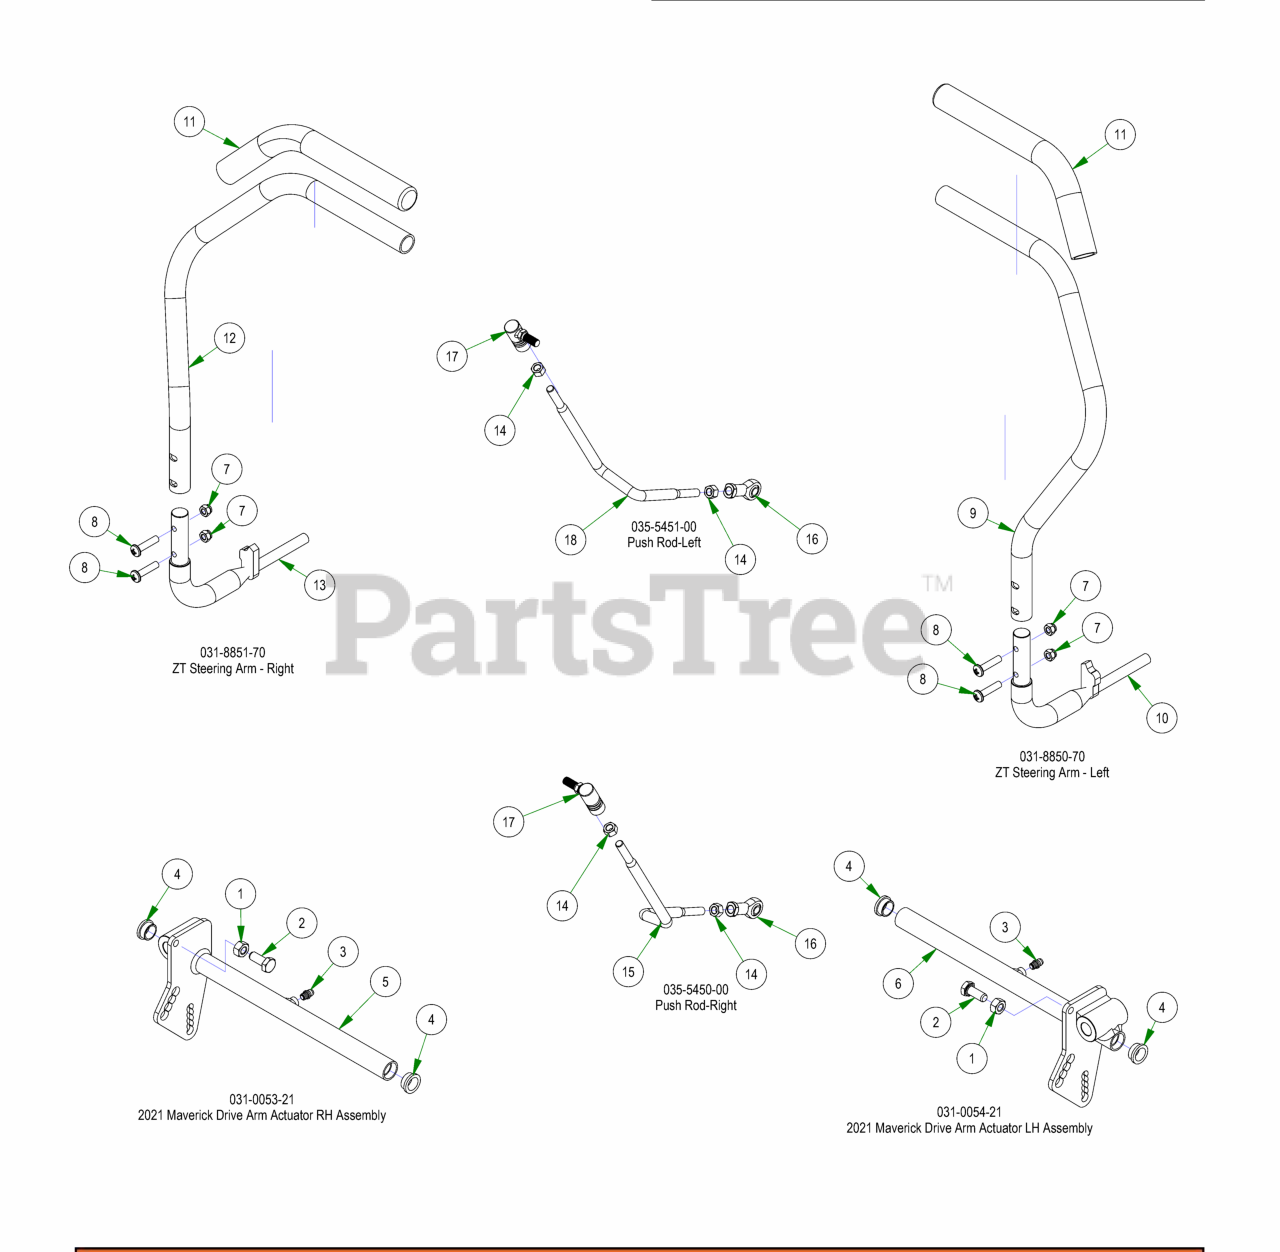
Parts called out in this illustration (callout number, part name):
1	5/16-18 HEX NUT ZINC
2	5/16-18 X 3/4 HEX CAP SCREW (GR.5) ZINC
3	1/4" Press in Grease Fitting
4	2019 Drive Arm Bushing
5	2021 Drive Actuator RH Weldment
6	2021 Drive Actuator LH Weldment
7	5/16-18 NYL INS L/N ZC
8	5/16-18 x 1 3/8" Futton Head Torx Drive Bolt
9	ZT Direction Steering Arm (Left)
10	Steering Arm Elbow (Left)
11	Rubber Grip
12	ZT Direction Steering Arm (Right)
13	Steering Arm Elbow (Right)
14	3/8" Fine Threaded Jam Nut
15	Push Rod - Right (Rod Only)
16	Spherical Rod End - Outlaw
17	Quick Release Ball Joint
18	Push Rod LH (Rod Only)
